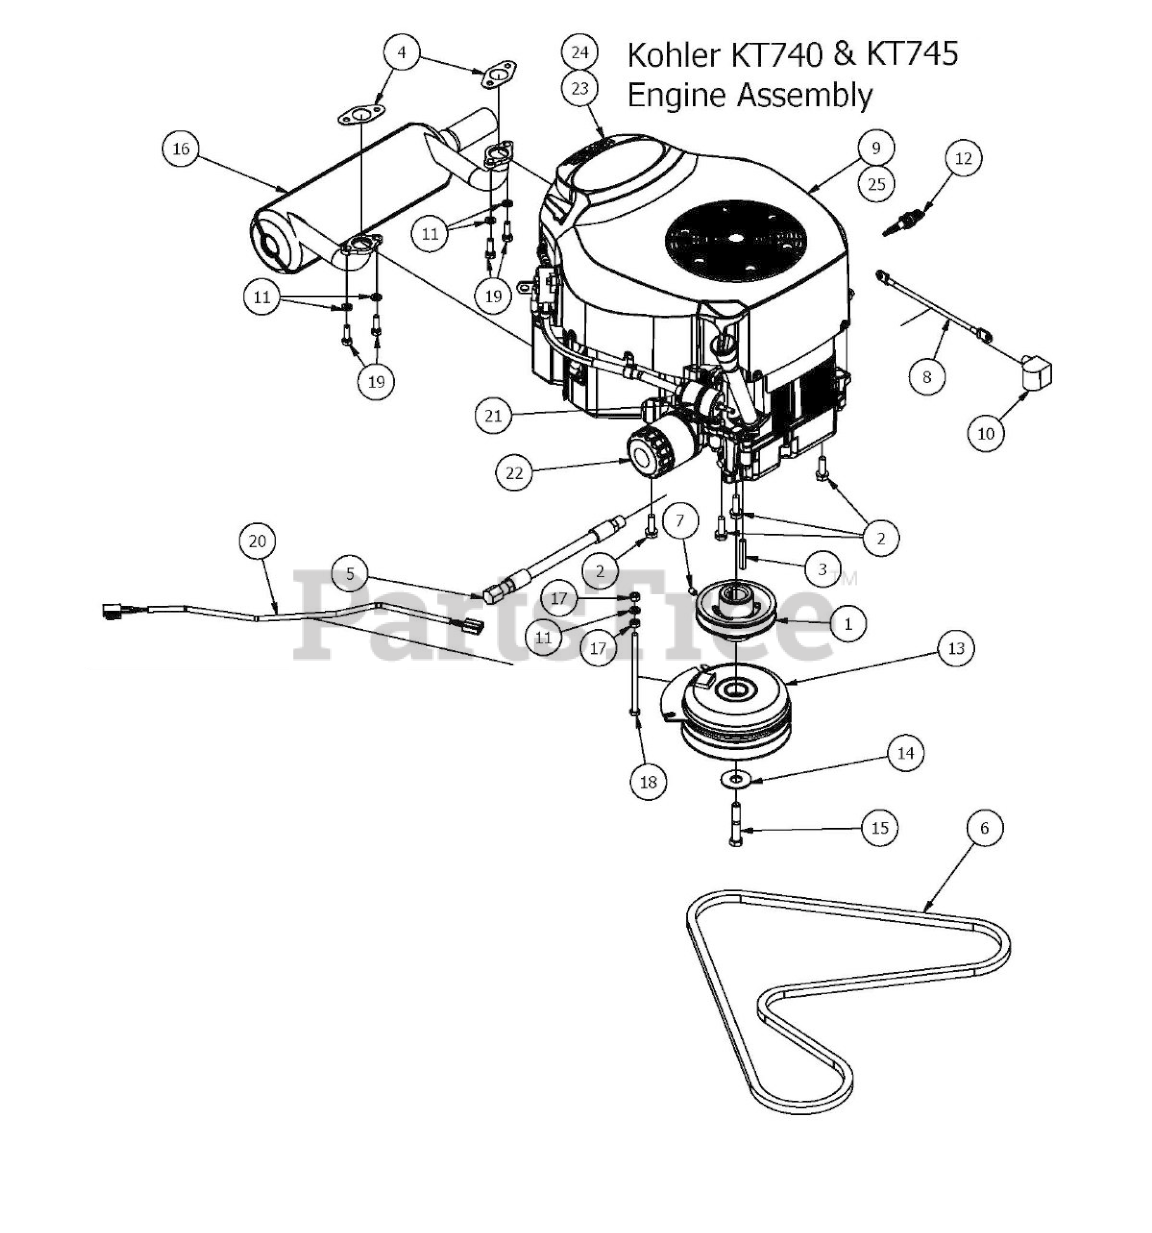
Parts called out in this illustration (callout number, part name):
1	4 3/4 Motor Pulley
2	3/8 x 1 1/8 bolt
3	1/4 x 2 Square key Stock
4	Exhaust Gasket
5	Oil drain Hose
7	5/16 Set Screw
8	Ground Cable
9	Kohler KT740cc Engine
10	Black Boot For Ground Cable
11	5/16" Lock Washer
12	Spark Plug
13	Clutch Assembly
14	Type B Plain Washer
15	7/16"-20 x 2.5" Hex Bolt Gr. 8
16	Kohler Muffler
18	5/16-18 x 5-1/2 GR 5 Hex Bolt
19	5/16" x 1" Bolt
20	Clutch Pigtail
21	Universal Inline Fuel Filter
22	725 & 747 Kohler Oil Filter
23	725 & 747 Kohler Precleaner
24	725 & 747 Kohler Air Element
25	Kohler KT745cc Engine
